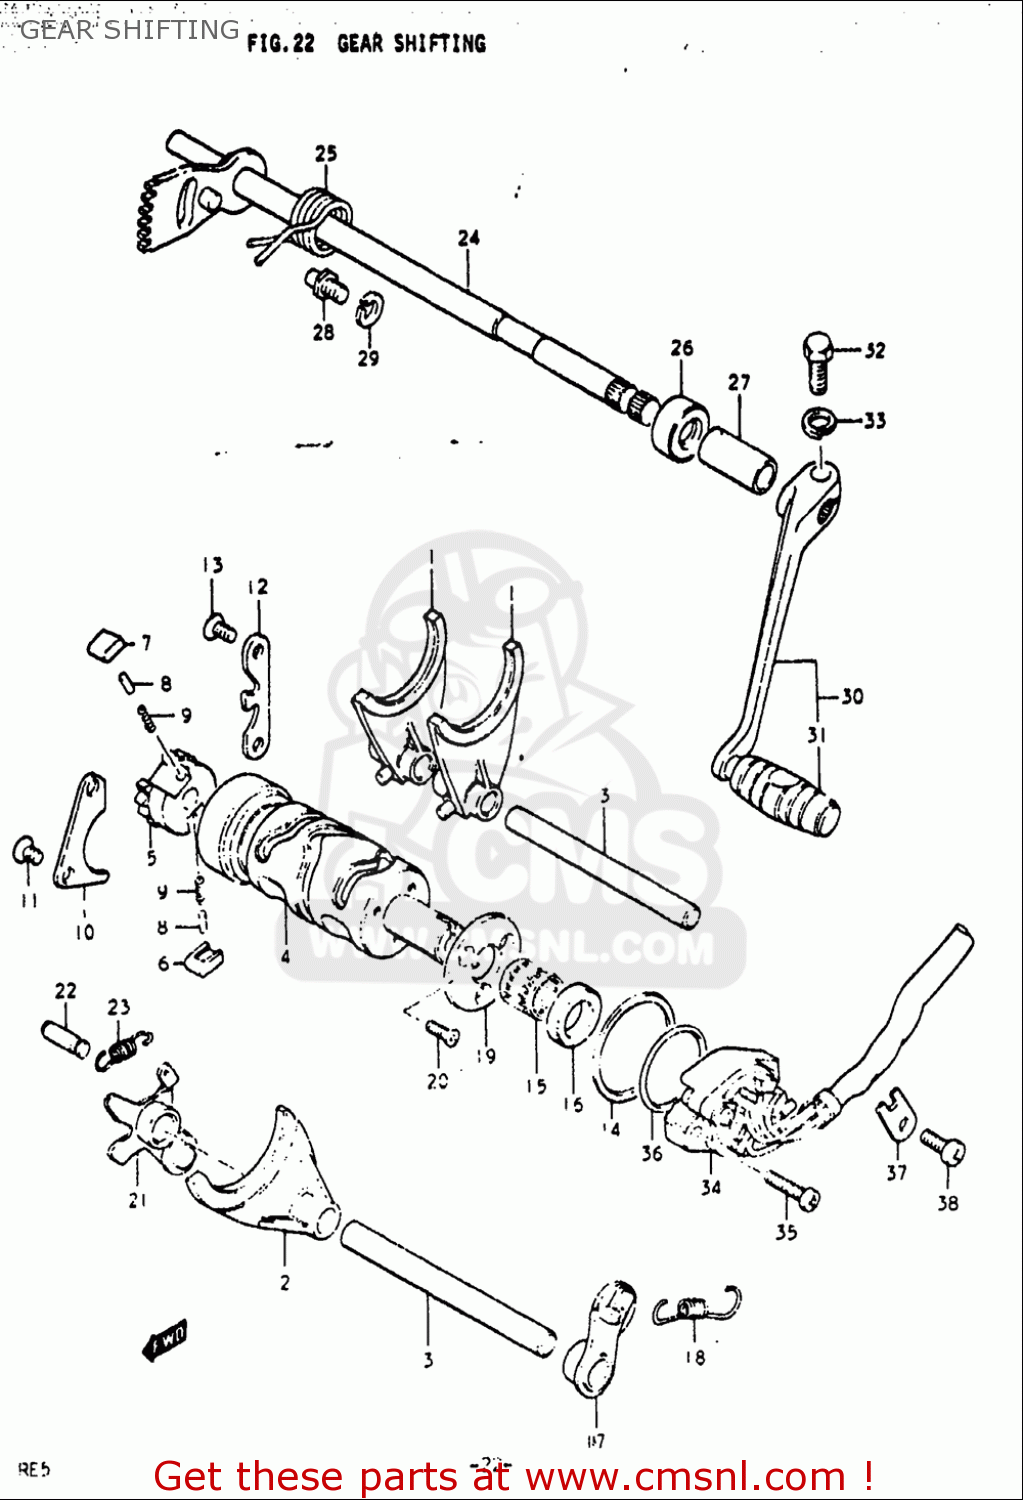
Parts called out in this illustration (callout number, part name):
3	SHAFT,GEAR SHIFT FORK
5	GEAR,GEAR SHIFT CAM DRIVEN
6	PAWL,GEAR SHIFT NO.1
7	PAWL,GEAR SHIFT NO.2
8	PIN(5X8)
9	SPRING
11	SCREW
12	GUIDE,GEAR SHIFT CAM
13	SCREW
14	WASHER(40X45X1)
15	BEARING(16X22X12)
16	SEAL,OIL(16X24X7)
20	SCREW
25	SPRING
26	SEAL,OIL (12X22X9)
27	CUSHION
28	STOPPER,GEAR SHIFT ARM
29	WASHER,LOCK
31	RUBBER,GEAR SHIFT PEDAL
32	BOLT
33	WASHER,LOCK
35	SCREW
36	O RING(D:1.9,ID:27.7)
38	SCREW
